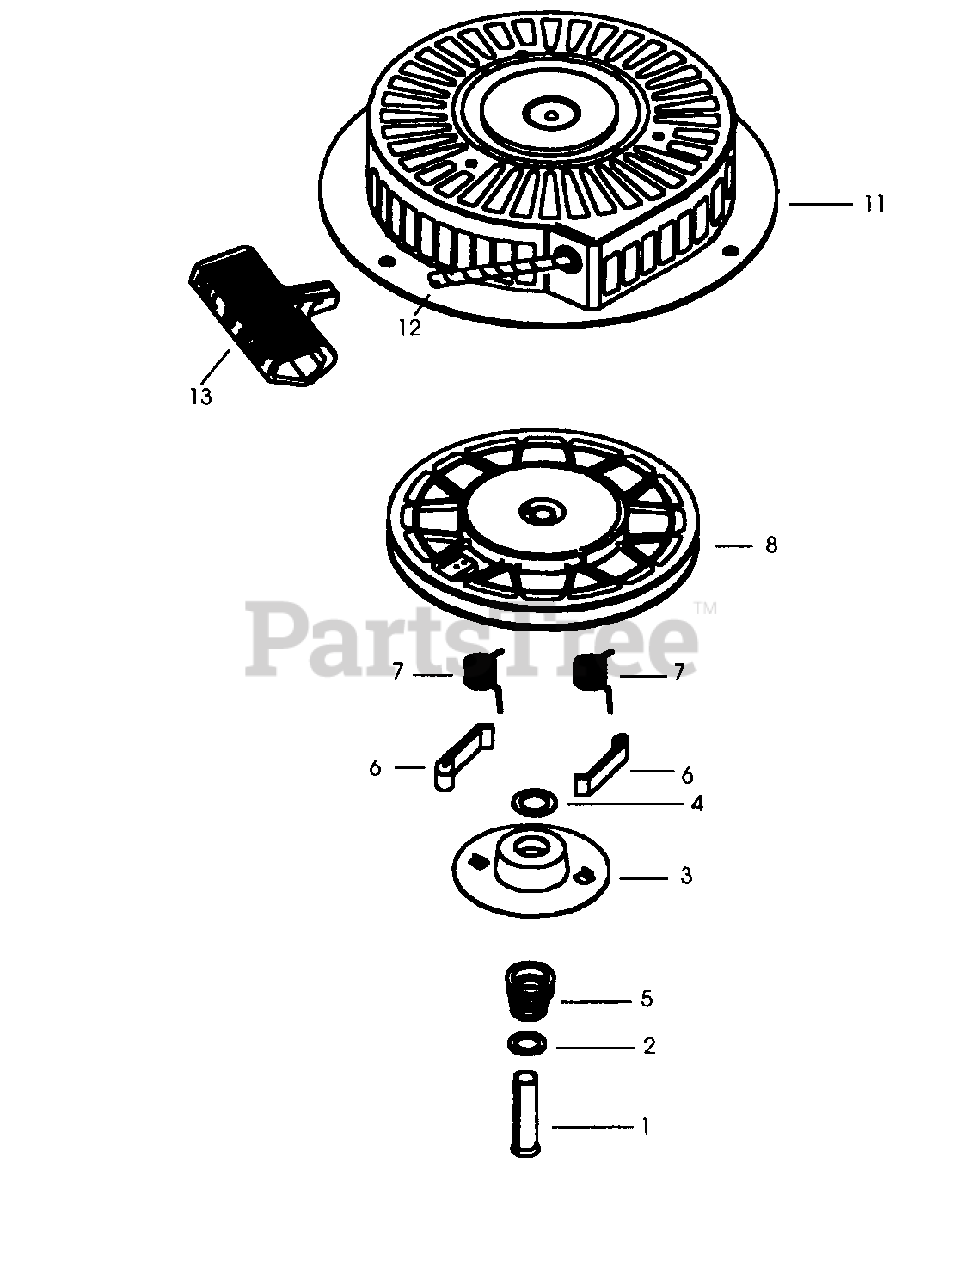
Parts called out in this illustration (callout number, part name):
1	Spring Pin
5	Brake Spring
6	Starter Dog
7	Dog Spring
8	Pulley 8 Rewind Spring Ass'y.
11	Starter Housing Ass'y.
12	Starter Rope (98" x 9/64" Dia.)
13	Starter Handle
